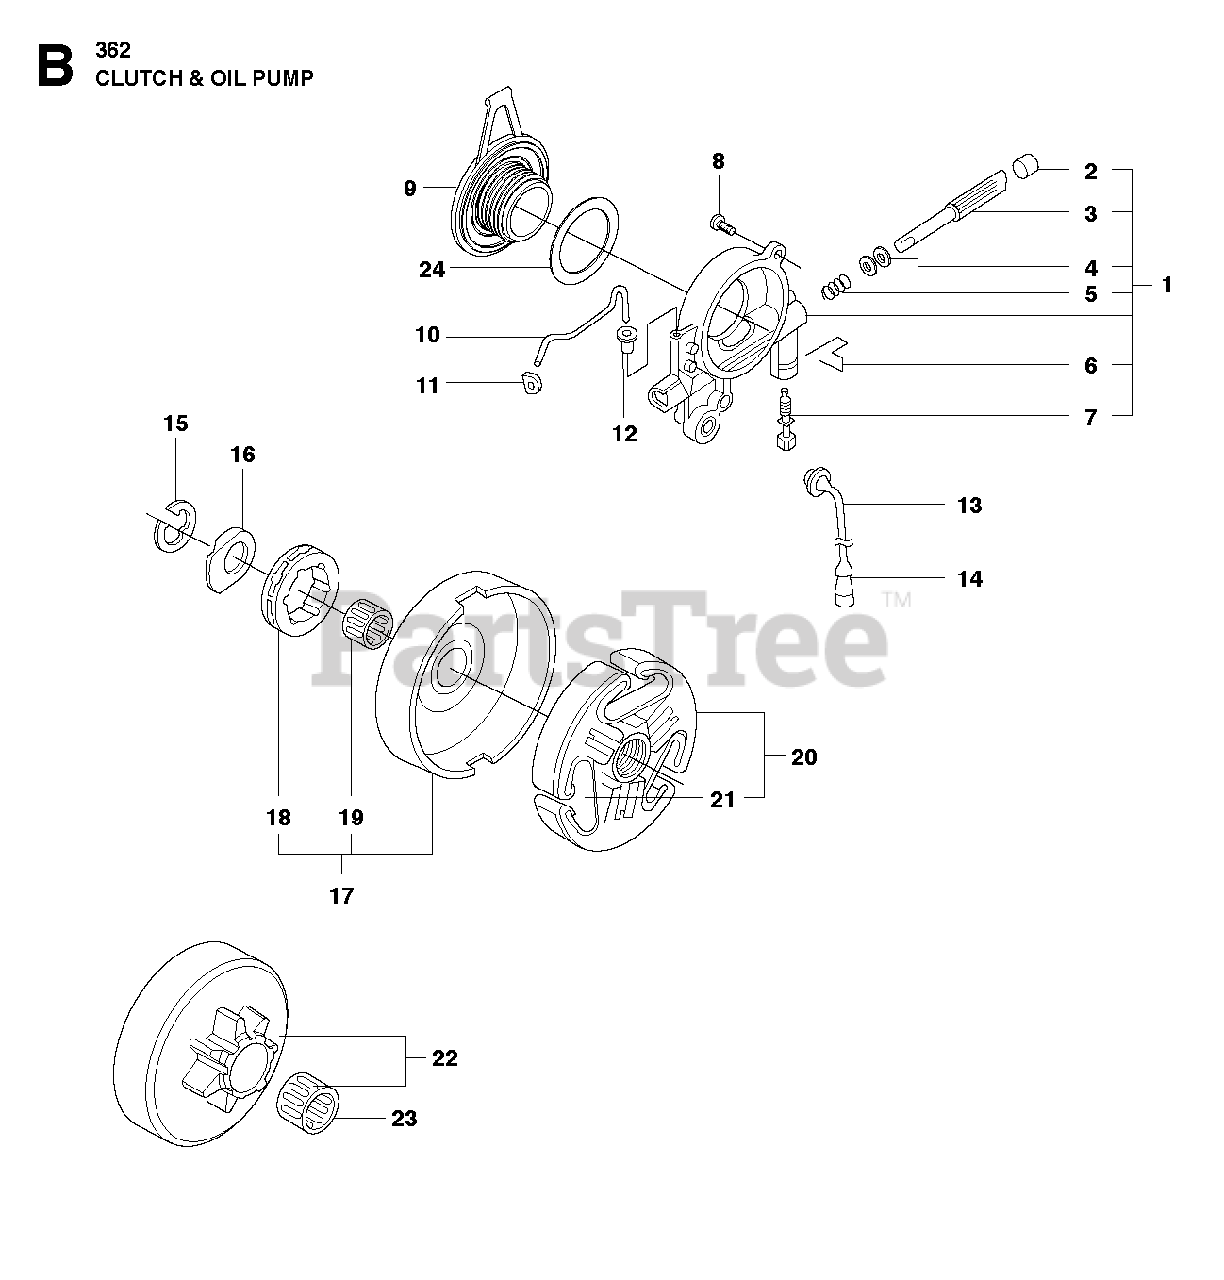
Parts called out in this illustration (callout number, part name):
1	OIL PUMP
2	PLUG
3	PUMP PISTON
4	WASHER 6.1X9
5	SPRING
6	SPRING CLIP
7	SCREW
8	SCREW MC6S 5X16
9	OIL PUMP DRIVE
14	OIL SCREEN
15	RETAINING RING
17	CLUTCH DRUM
18	68210 RIMSPROCKET
18	Power Mate Rim
19	CLUTCH DRUM BEARING
20	CLUTCH
22	CLUTCH DRUM
23	CLUTCH DRUM BEARING
